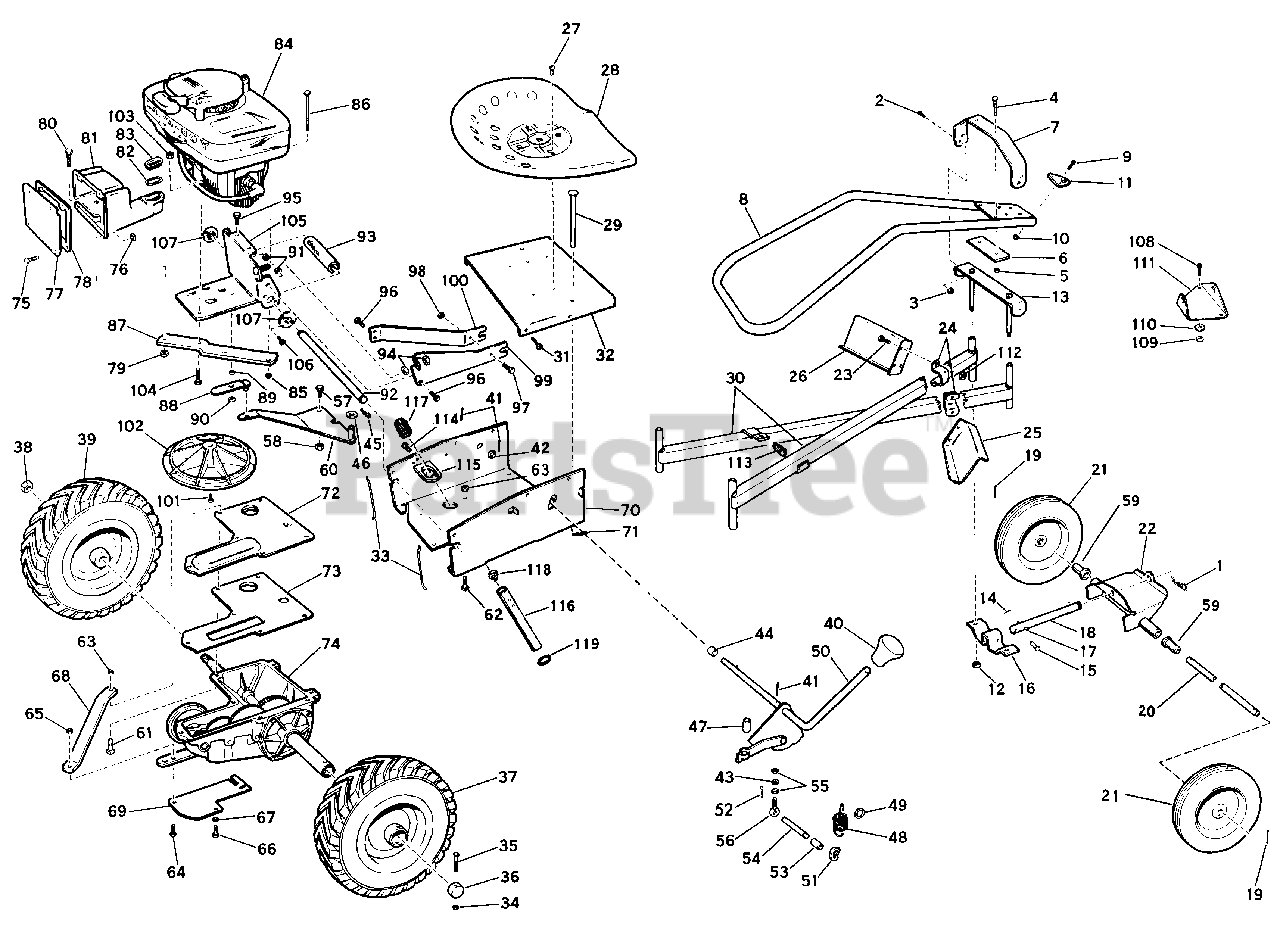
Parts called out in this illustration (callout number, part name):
1	Hair Pin-Transverse Pivot Rod
2	Bolt-Handle
3	Nut-Nylok
5	Nut-Nylok
6	Clamp-Handle Pivot Bracket
7	Bracket-Handle Pivot
8	Handle, Tube and Tongue Bracket Assembly
9	Screw-Machine (Tongue)
10	Nut-Nylok (Tongue)
12	Nut-Nylok
13	Top Pivot Bracket and Pin Assy.
14	Pin-Cotter (Transverse Pivot Rod Pin)
15	Pin-Transverse Pivot Rod
16	Pivot Bracket-Frame, Bottom
17	Groove Pin
18	Rod-Transverse Pivot
19	Pin-Spiral
20	Axle-Wheel Attachment
21	Wheel and Tire Assy., 8 x 1.75
22	Axle and Bracket Assembly (Front Wheel Attachment)
23	Screw-Foot Bracket
24	Bracket-Foot Pedal Clamp
25	Foot Pedal and Plate Assy., Right
26	Foot Pedal and Plate Assembly, Left
27	Screw-Seat to Cover
28	Seat Assembly
29	Pin-Rear Pivot, Frame
30	Tube and Pivot Assembly
31	Screw-Thread Cutting (Shroud to Cover)
32	Cover-Shroud
33	Spring-Engine Mounting Shaft
34	Nut-Nylok, Wheel Bolt, Right
35	Screw-Wheel, Right
36	Plug-Wheel Hub
37	Wheel and Tire Assy., Right
38	Nut-Nylok, Left Wheel
39	Wheel and Tire Assy., Left
40	Knob-Speed Control
41	Pin-Cotter, Speed Control Rod
42	Washer-Speed Control
43	Lockwasher-Shakeproof
44	Roller-Speed Control
45	Hair Pin-Bell Crank Pin
46	Washer-Bell Crank Pin
47	Sleeve-Rubber, Bell Crank
48	Spring-Clutch
49	Washer-Clutch Spring
50	Speed Control Rod and Lever Assembly
51	Clip-Clutch Spring
52	Hair Pin-Ramp Pin
53	Roller-Ramp Pin
54	Pin-Ramp
55	Nut-Eye Bolt
56	Bolt-Eye, Ramp Pin Adjustment
57	Bolt-Bell Crank
58	Nut-Nylok (Bell Crank Shoulder Bolt)
59	Bearing-Wheel, Nylon
60	Bell Crank and Pin Assembly
61	Screw-Shroud
62	Screw-Shroud
63	Nut-Nylok, Shroud
64	Screw-Brace, Bar
65	Nut-Nylok, Guard to Drawbar
66	Screw-Guard to Housing
67	Lockwasher-Guard to Housing Screw
68	Brace-Drawbar
69	Guard-Roller
70	Shroud-Frame
71	Hair Pin-Rear Pivot Frame
72	Plate-Transmission
73	Gasket-Transmission Plate
74	Transmission Assembly
75	Screw-Muffler
76	Nut-Muffler Screw
77	Cover-Muffler
78	Gasket-Muffler
79	Nut-Hug Lock
80	Screw-Muffler Clamp
81	Muffler
82	Gasket-Exhaust
83	Sleeve-Exhaust Gasket
84	Engine-Model C-50
85	Nut-Muffler Clamp to Cylinder
86	Screw-Muffler Clamp to Cyl.
87	Clamp-Muffler
88	Bell Crank Link and Pin Assembly
89	Sleeve-Bell Crank Link
90	Washer-Plain
91	Nut-Nylok
92	Shaft-Engine Mounting Plate
93	Oiler-Shaft
94	Nut-Clutch Adjusting
95	Screw-Thread Cutting, Engine Mounting Plate to Arm. Plate
96	Bolt-Clutch Arm and Clutch Arm Brace
97	Screw-Machine Hex Hd.
98	Nut-Nylok
99	Arm-Clutch
100	Brace-Clutch Arm
101	Screw-Cap Disc
102	Disc-Drive
103	Nut-Nylok, Engine Mtg. Screw
104	Screw-Engine Mounting
105	Engine Mounting Plate, Adjusting Screw and Bearing Assembly
106	Screw-Self Tapping
107	Bearing-Engine Mounting
108	Screw-Mower Mounting Plate
109	Nut-Mower Mounting Plate
111	Plate-Mower Mounting
112	Nut-Foot Pedal Screw
113	Spring-Tube and Pivot Assy.
114	Screw-Self Tapping
115	Bracket-Oil Filler
116	Tube-Oil Filler
117	Cap Tube-Oil Filler
118	Spring-Oil Filler
119	Seal, Tube-Oil Filler
